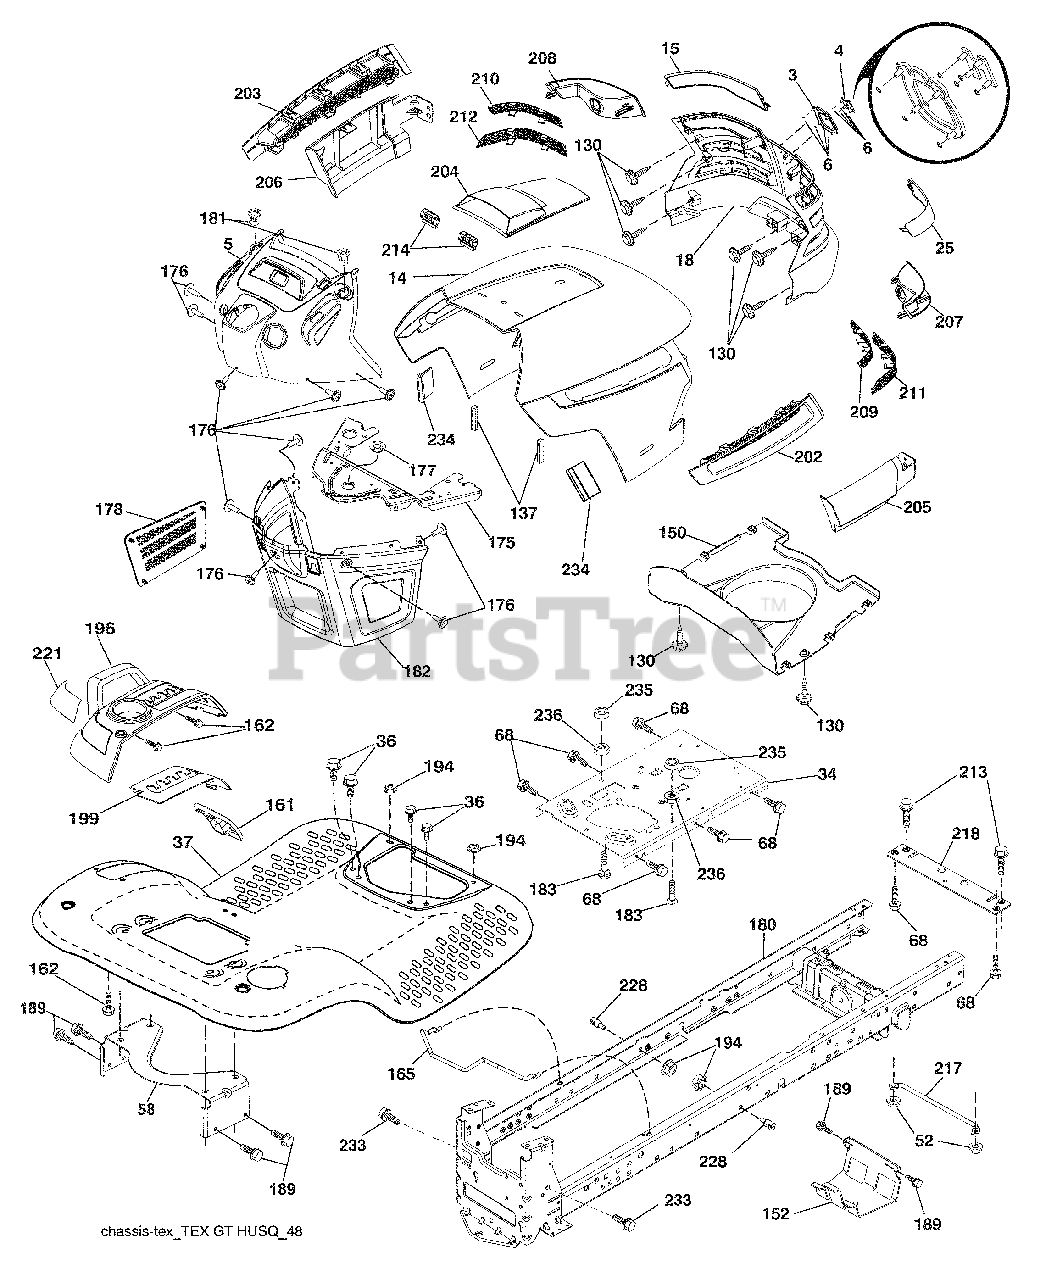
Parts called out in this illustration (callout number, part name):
3	Trim, Husq.
4	Logo
14	Hood
18	Grille/Lens Asm.
34	Plate Engine
36	Screw 5/16-18 x 3/4
37	Fender
52	Nut Lock 5/16-18
58	Drawbar Upper 2 pc Lrg. Fender
68	Screw Thdrol 5/16-18 x 1/2
130	Screw 10 x .750 BOS Thread
137	Bumper Dash
152	Shield Browning
161	Window, Fuel
162	Screw Hex Wsh 1/4 x 1/2 unc
165	Support Tank Rear
175	Crossmember
176	Screw 10-24 x 5/8
177	Bushing Steering
178	Cargo Net Asm.
181	Bushing Mtg. Fender Crgo
182	Dash Lower
183	Bolt Fin Hex 5/16-18 unc x 1-1/4
189	Screw 5/16-18 x 3/4
194	Nut Lock Hex Flange 5/16-18
196	Console Asm. Deck Lift
199	Plate Deck Lift
202	Vent Side Hood RH
203	Vent Side Hood LH
204	Vent Top Hood
205	Skirt Hood Side RH
206	Skirt Hood Side LH
209	Insert Hex Top RH
210	Insert Hex Top LH
211	Insert Hex Bottom RH
212	Insert Hex Bottom LH
213	Bolt 5/16-18 x 3/4
214	Clip Retainer Tinner
218	X-Piece Hood Stop
221	Reflector LH
228	Stud Fastner
233	Bolt, Shoulder
234	Bumper Hood
235	Spacer Fender
236	Nut Lock 5/16-18 unc
